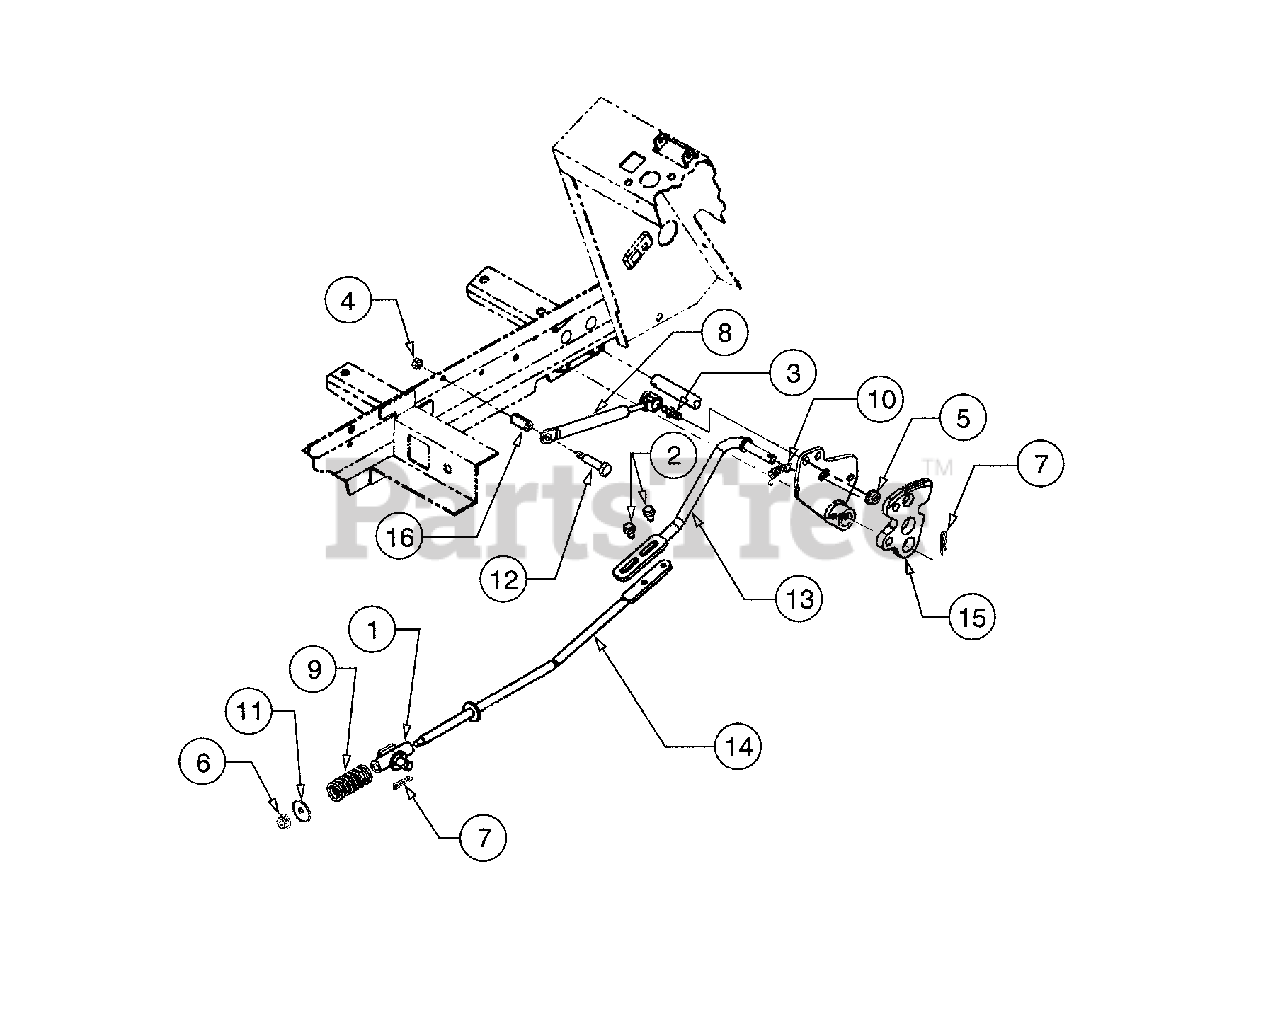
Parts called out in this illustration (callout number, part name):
1	Pivot Assembly
2	Screw, Hex Wash Hd Tapp, 1/4-20 x .5
3	Screw, Ball, 5/16-18 x .56
4	Nut, Hex Sems, 1/4-20
5	Nut, Hex Flange Lock, 5/16-18 GR5
6	Nut, Hex Flange Lock, 1/4-20
7	Pin, Internal Cotter
8	Cylinder, Damper
9	Spring, Compression, .63 ID x 2.0 Lg
10	Spring, Extension, 3/8 OD x 1.44
11	Washer, Flat, .265 x 1.0 x .030
12	Bolt, Shoulder, .374 Dia x 1.375
13	Rod, Front Control
14	Rod, Rear Hydro Control
15	Plate, Cruise
16	Spacer, Split Tubing, .375 ID x 1.04
